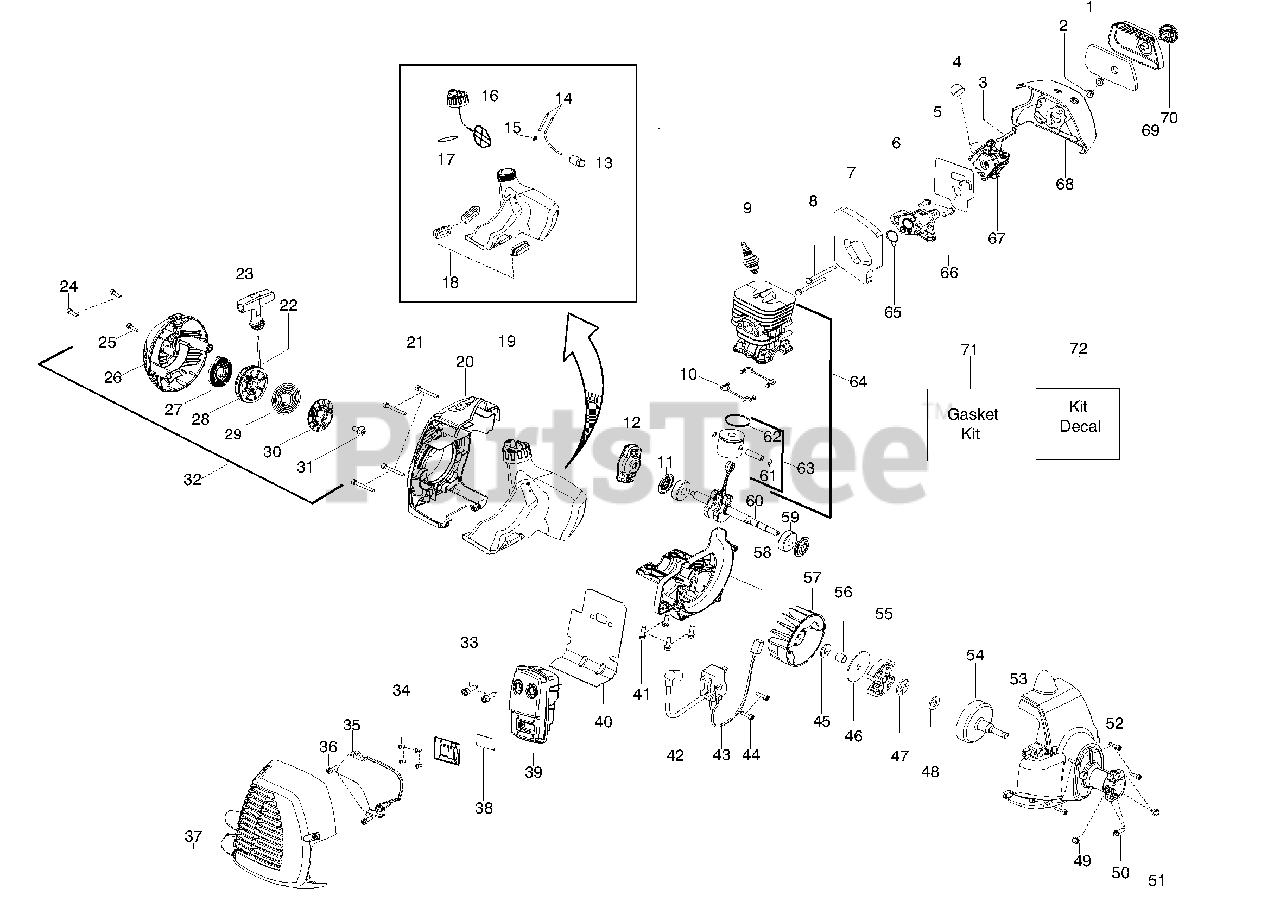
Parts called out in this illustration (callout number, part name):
2	Nut - Carb. Screw
3	Lever - Choke
4	Bulb - Purge
5	Kit - Carb. Gasket
6	Adaptor - Carb.
7	Foam - Gasket (kit)
9	Plug - Spark (RCJ-8Y)
10	Seal - Cylinder (kit)
11	Seal - Crankshaft (kit)
12	Assy - Starter Pawl
13	Assy - Fuel Filter
14	Kit - Fuel Line
15	Fitting - Fuel Line
16	Assy - Cap w/ret.
17	O-Ring - Fuel Cap (kit)
18	Isolator - Fuel Tank
19	Kit - Fuel Tank Assy.
20	Shroud - Rear (KIT)
22	Kit - Rope
23	Handle - Starter
26	Starter Hsg. (KIT)
27	Kit - Spring
28	Kit - Starter Pulley
29	Spring - Driver
30	Pulley - Driver
32	Assy - Starter Hsg.
33	Bolt - Muffler
34	Screw
35	Shield - Heat
37	Kit - Muffler Guard
38	Kit - Spark
39	Kit - Muffler
40	Gasket - Paper Met.(kit)
42	Module - Ignition
43	Assy - Leadwire
46	Washer - Clutch
47	Bearing - Thrust
48	Washer - Thrust
49	Screw
50	Screw
53	Assy - Fan Housing
54	Assy - Clutch Drum
55	Assy - Clutch
58	Crankcase - Cast
60	Assy - Crankshaft
61	Retainer - Piston Pin
62	Ring - Piston
63	Kit - Piston
64	Kit - Cyl./Piston
65	Seal - adaptor (kit)
67	Kit - Carb.
68	Airbox
69	Cover - Air Box
70	Assy - Knob
71	Kit - Gasket
72	Kit - Decal
